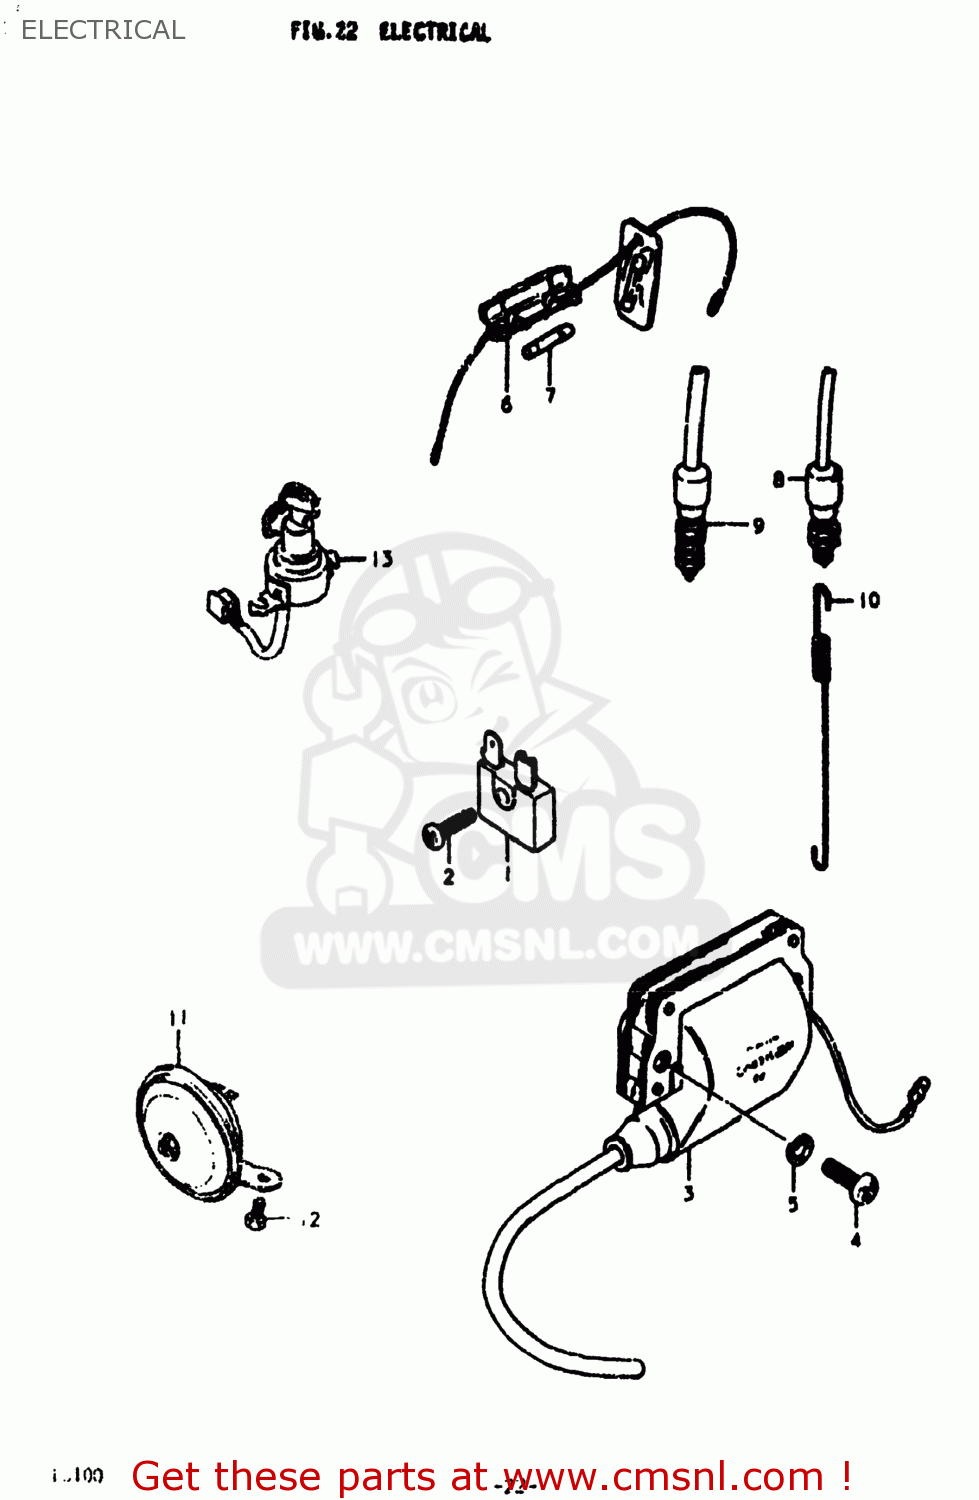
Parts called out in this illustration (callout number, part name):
1	RECTIFIER ASSEMBLY
2	SCREW
3	COIL ASSEMBLY,IGNITION
4	SCREW
5	LOCK WASHER
6	BOX ASSEMBLY,FUSE
7	FUSE(10A)
8	SWITCH ASSY, STOP LAMP
9	SWITCH ASSEMBLY,STOP LAMP
10	SPRING
11	HORN ASSEMBLY
12	BOLT
